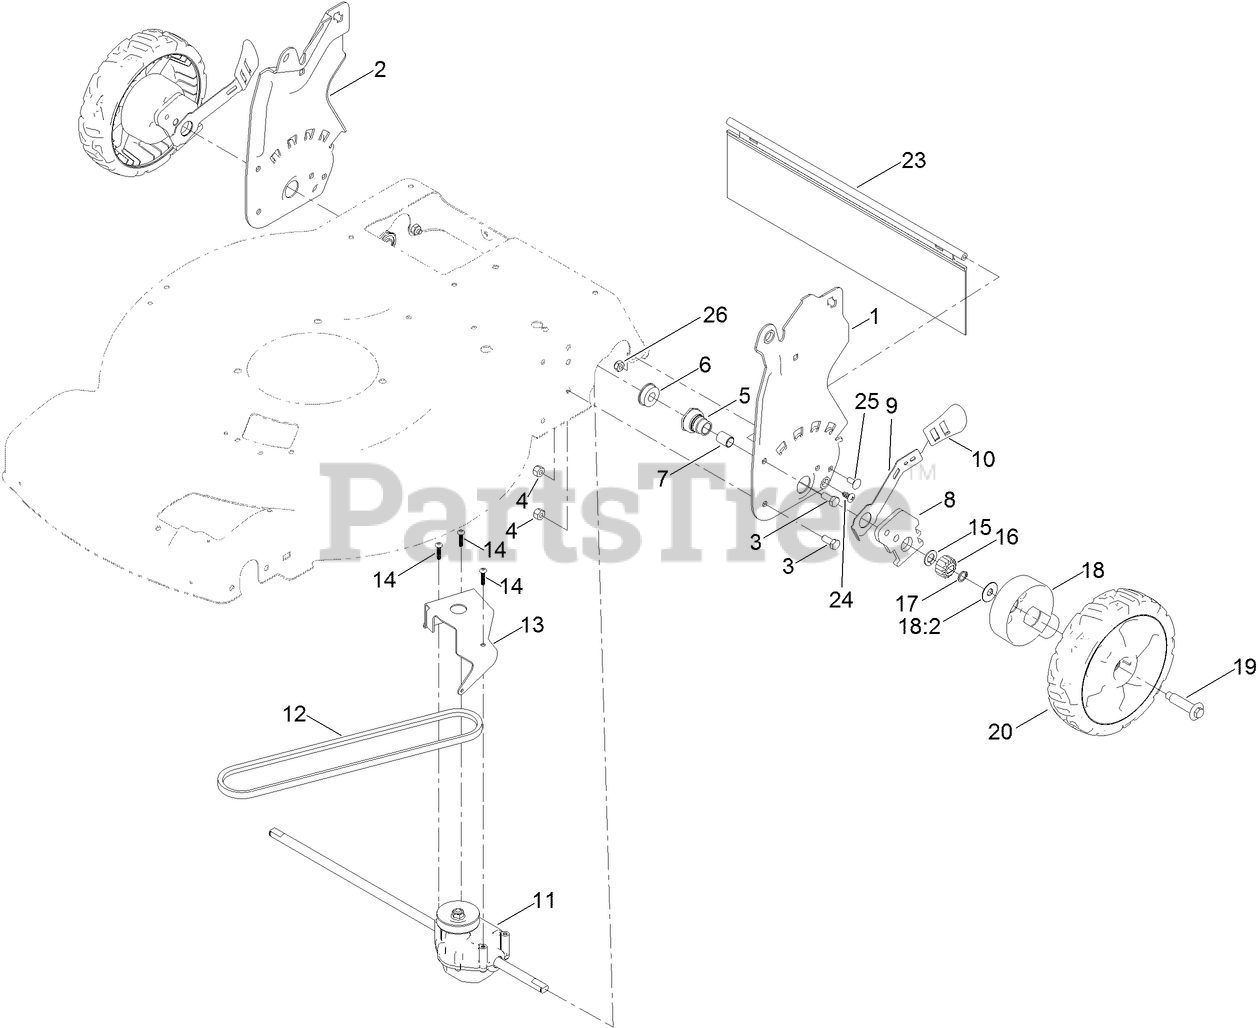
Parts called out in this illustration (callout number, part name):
1	PLATE-HOC, LH
2	PLATE-HOC, RH
3	SCREW-HH
4	NUT-LOCK, NI
5	RETAINER-BUSHING, HOC
6	BEARING-BALL
7	BUSHING-SLEEVE
8	ARM-PIVOT, REAR
9	ARM-SPRING
10	KNOB-HOC
11	TRANSMISSION ASM
12	BELT-V
13	BRACKET-TRANSMISSION
14	SCREW-PLASTITE
15	WASHER-THRUST
16	GEAR-PINION, 15T
17	RING-RETAINING
18	GEAR COVER ASM
18:2	WASHER-STEPPED
19	BOLT-SHOULDER
20	WHEEL GEAR ASM, 8IN
23	SHIELD-TRAILING
24	SCREW-PTH
25	SCREW-CARR
26	NUT-LOCK, NI
